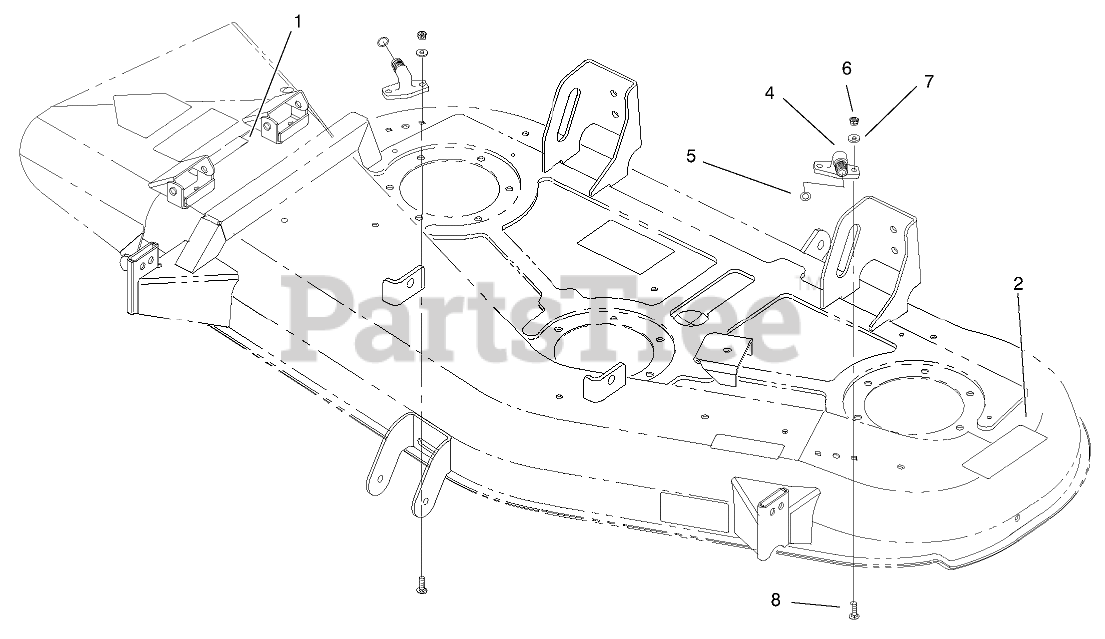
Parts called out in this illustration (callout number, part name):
1	DECAL-DANGER
2	DECAL-DANGER
5	O-RING
6	NUT-LOCK, NI
7	WASHER-FLAT
8	BOLT-CARR
